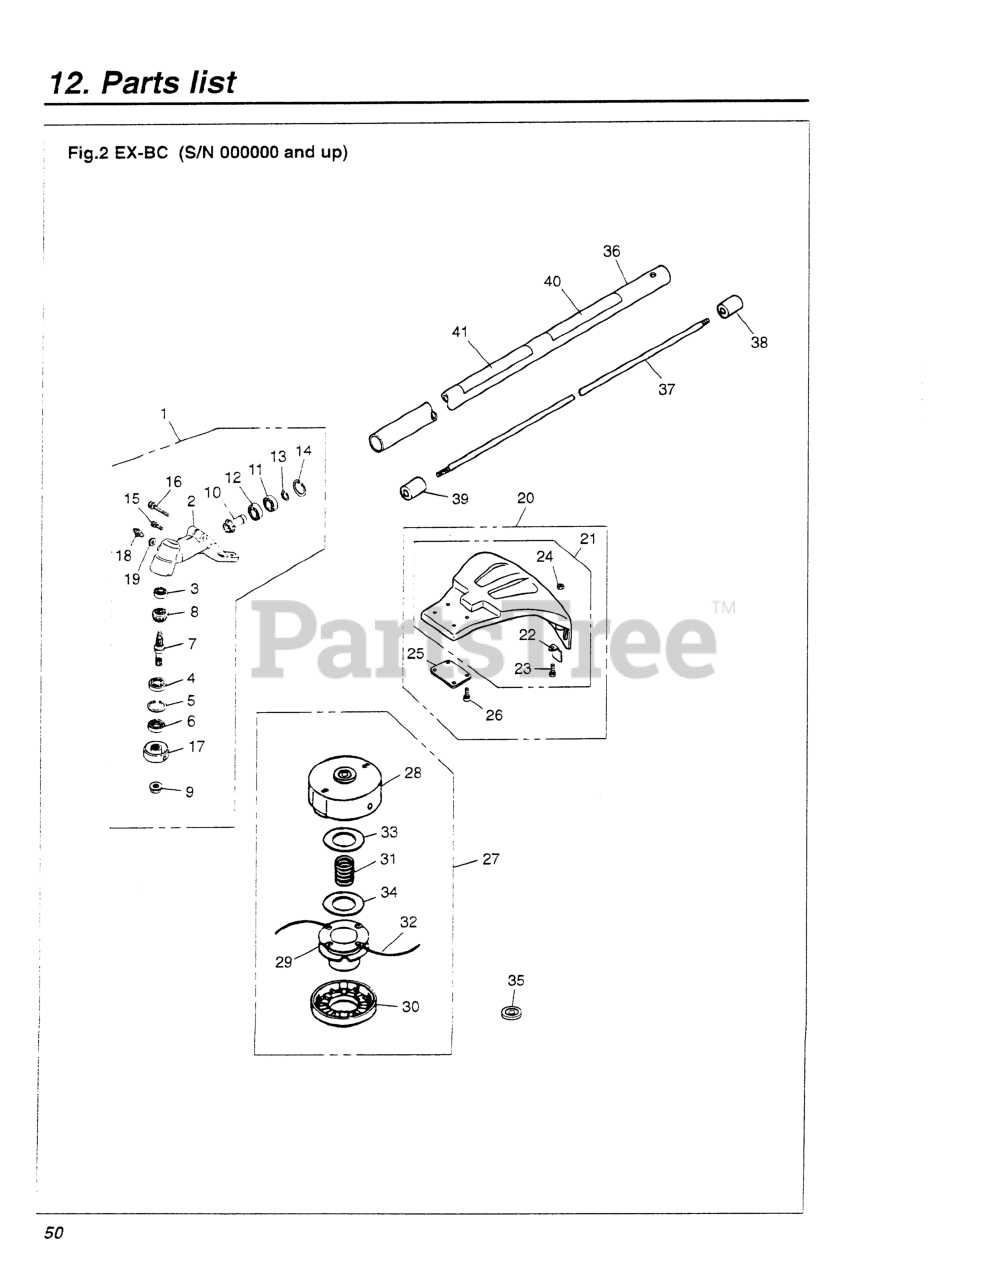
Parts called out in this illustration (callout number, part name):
1	GEARCASE ASSY (RPLS -13000)
2	GEARCASE
3	BEARING (RPLS T3300-13521)
4	BEARING (RPLS T3403-13510)
5	RING, SNAP, M26 X 1.2
6	SEAL, OIL
7	SHAFT
8	GEAR
9	NUT
10	PINION
11	BEARING (RPLS T3300-13531)
12	BEARING (RPLS T3403-13530)
13	RING, SNAP (RPLS T3300-13330)
14	RING, SNAP, M24 x 1.2
15	BOLT, M5 X 10
16	BOLT
17	HOLDER (A)
18	FITTING, GREASE
19	WASHER, M6 X .8
20	GUARD ASSY (RPLS -24000)
21	GUARD COMP (RPLS. -24100)
22	BLADE (RPLS T3002-24120)
23	SCREW
24	NUT
25	PLATE
26	BOLT (USE 3310-31720)
27	4
28	CASE (RPLS -15112)
29	HOLDER, CORD (RPLS -15141)
30	COVER (RPLS -15130)
31	SPRING (RPLS -99161)
32	CORD
33	PLATE, LARGE
34	PLATE, SMALL
35	HOLDER (B)
36	PIPE COMPLETE
37	SHAFT
38	JOINT, SHAFT (RPLS -12240)
39	SPACER
40	PLATE, NAME (BC-EX)
41	PLATE, CAUTION
